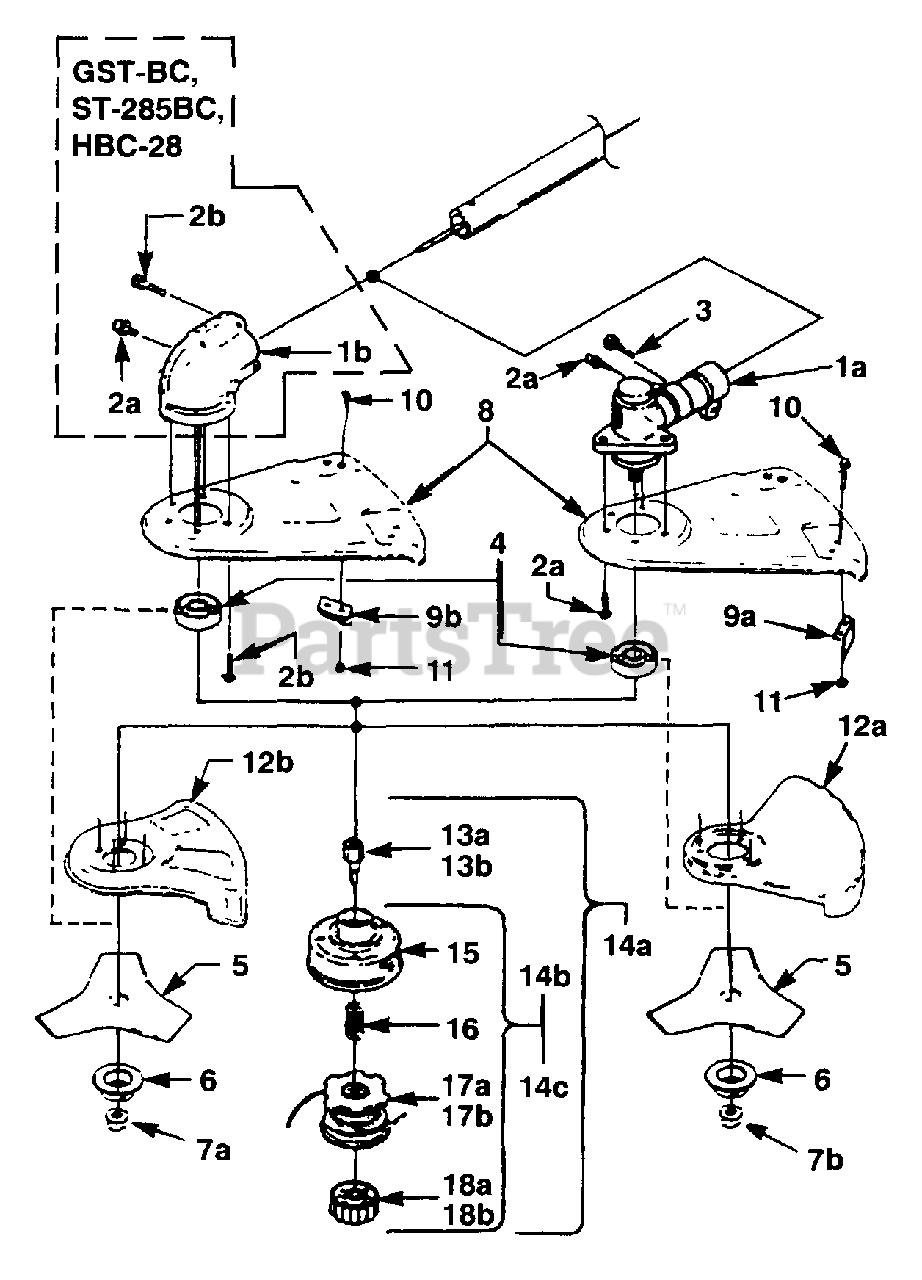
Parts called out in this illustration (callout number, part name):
1A	GEAR HEAD
1B	GEAR HEAD
2A	SCREW - Hex Hd (10-24 X 1/2")
2B	SCREW - Hex Hd (10-24 X 5/8")
2B	SCREW - Hex Hd (10-24 x 5/8)
3	SCREW - Socket Hd (10-24 X 1")
4	WASHER - Flanged
5	BLADE - Tri Arc
6	WASHER - Cupped, Lower
7A	NUT - Hex Locking (R.H.)
7B	NUT - Hex Locking (L.H.)
8	GRASS DEFLECTOR
9A	BLADE - Cut Off
9B	BLADE - Cut Off
10	SCREW - Mach. Hex Hd (10-24 X 3/8")
11	NUT - Hex (10-24)
12A	BLADE GUARD
12B	BLADE GUARD
13A	SHAFT ADAPTOR (L.H.)
13B	SHAFT ADAPTOR (R.H.)
14A	STRINGHEAD COMPLETE (.095" Line)
14B	STRINGHEAD COMPLETE (.095" Line)
14C	STRINGHEAD COMPLETE (.080" Line)
15	HOUSING & EYELET
16	SPRING - Compression
17A	SPOOL & STRING
17B	SPOOL & STRING
18A	SPOOL RETAINER (L.H.)
18B	SPOOL RETAINER (R.H.)
